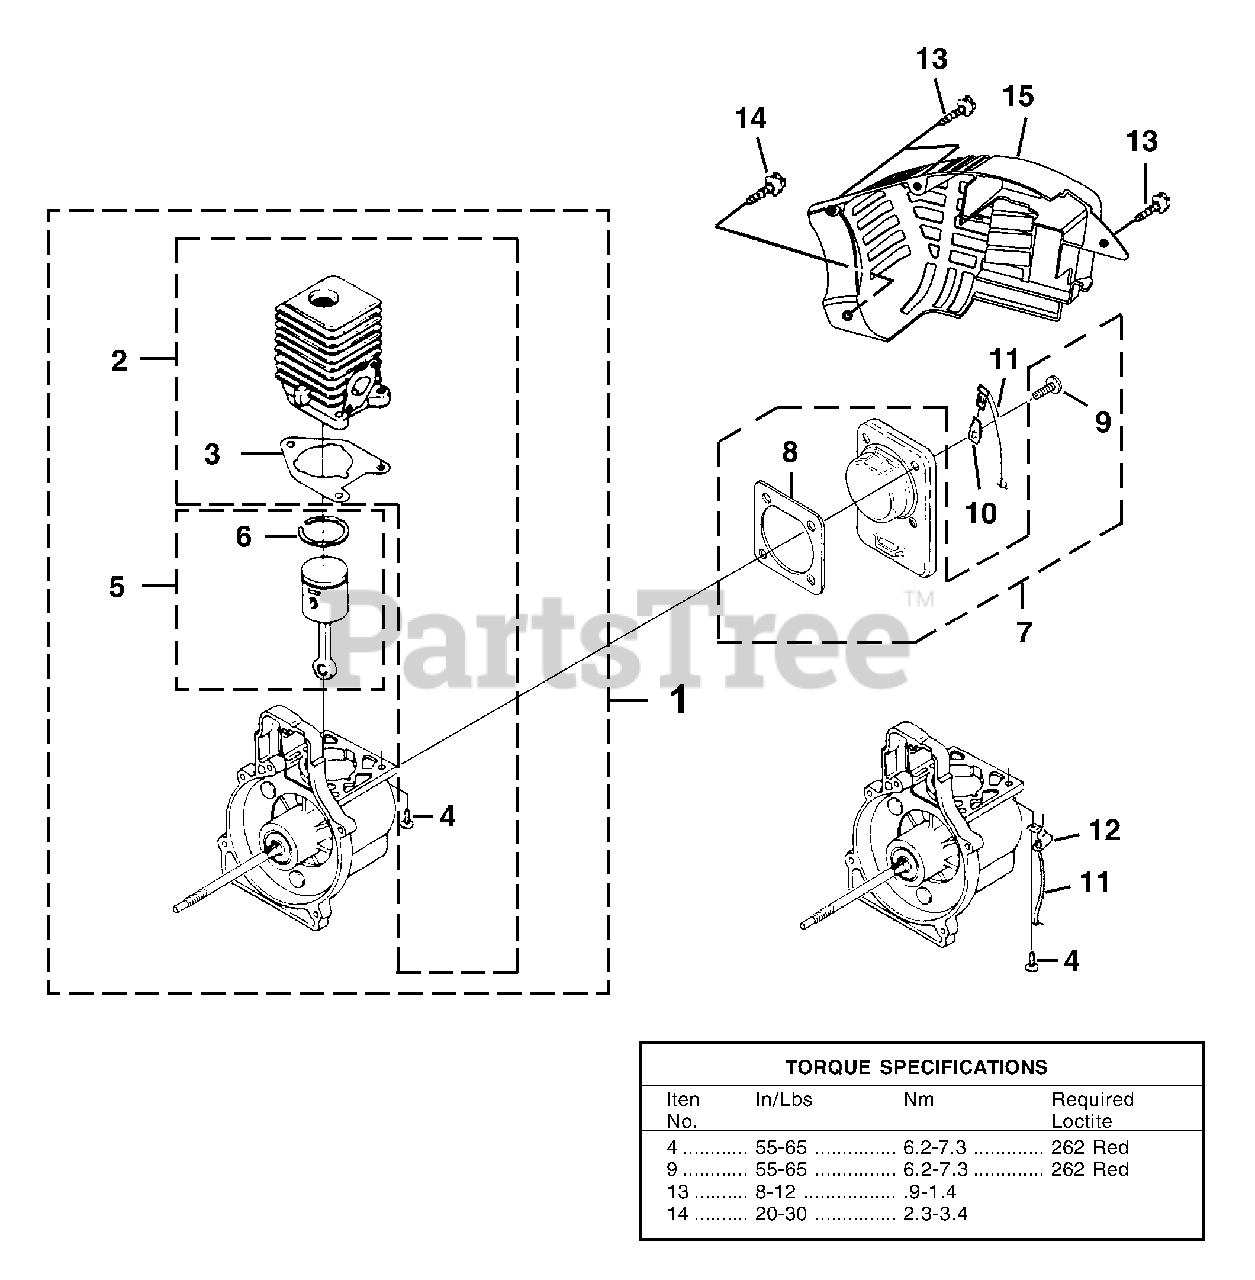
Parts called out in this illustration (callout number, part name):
1	SHORT BLOCK (25cc)
2	25 CC CYLINDER KIT
3	GASKET-Cylinder
4	SCREW, SEMS (12-24 x 3/4)
5	25 CC PISTON & ROD
6	RING-Piston
7	CRANKCASE COVER-Stamped Steel
8	GASKET-Crankcase
9	SCREW, SEMS (10-24 x .56)
10	TAB-Male
11	CABLE-Throttle w/Ignition Leads
12	CABLE BRACKET
13	SCREW-Thread Form. (#8 X 1/2")
14	SCREW-Thread Form. (#10 X 3/4")
